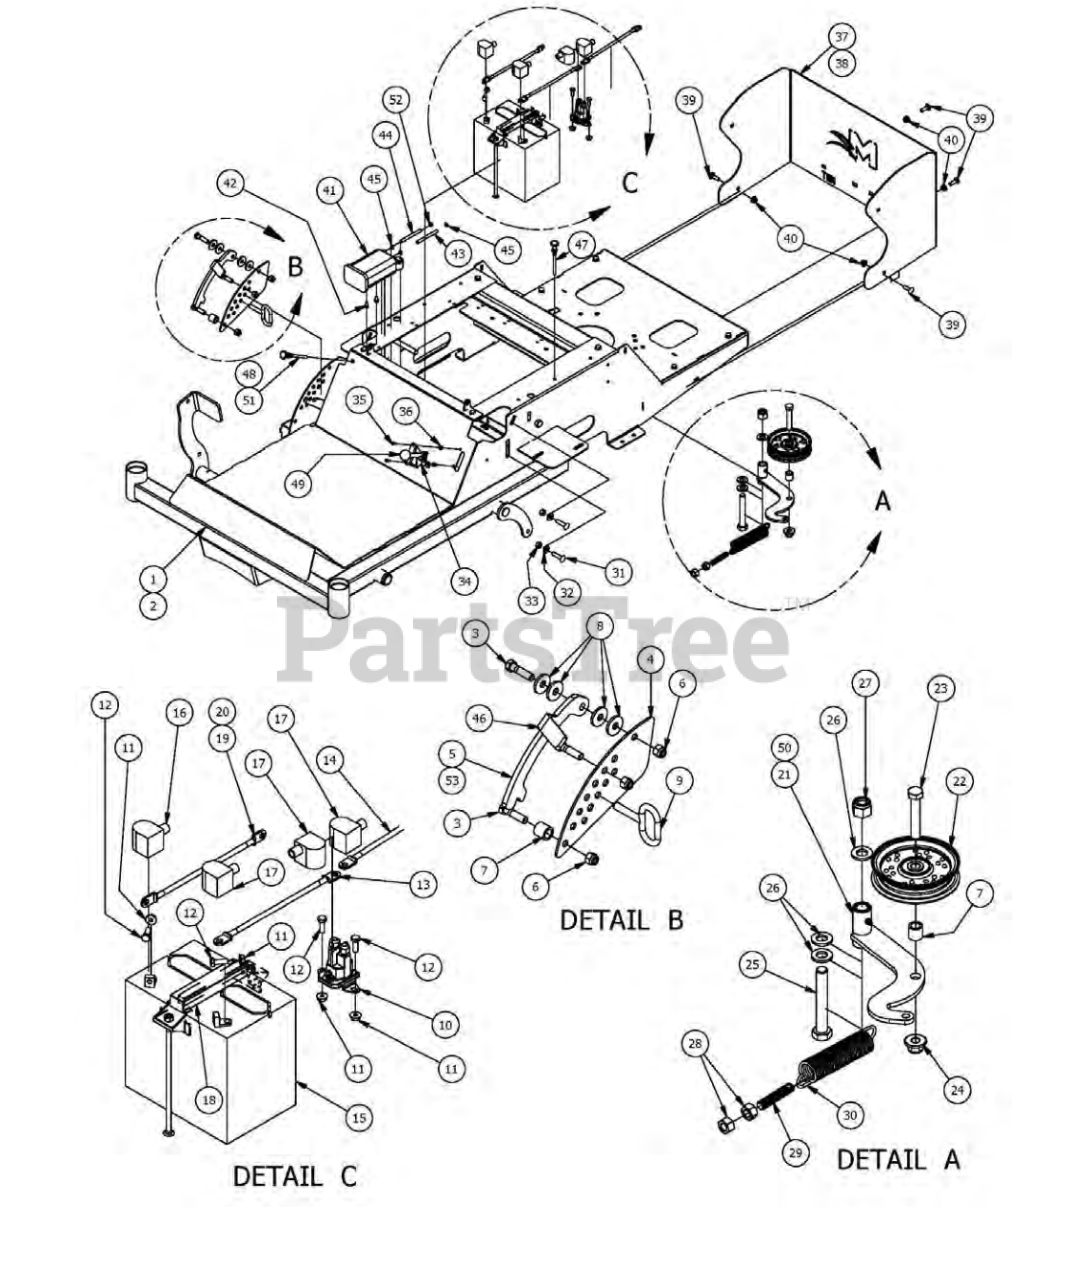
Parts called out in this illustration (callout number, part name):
1	48" MZ Frame
2	54" MZ Frame
3	3/8" x 1 1/2" Hex Bolt
4	MZ Height Indicator Plate
5	MZ Magnum Deck Level Lock Lever
6	3/8 Nylock Nut
7	Spacer 3/4 OD x 1/2 ID x 314 Length
8	390 ID Plastic Washer
9	Deck height lever pin
11	1/4-20 Hex Flange Nuts Zinc w/Serrations
12	1/4-20 x 3/4 GR 5 Hex Bolts Zinc
13	10" red battery cable
14	62" red cable
16	Black Boot For Ground Cable
18	Battery Hold Down
19	24" Ground Cable (21HP Briggs Only)
20	Ground cable
21	MZ Idler arm Bracket
22	43/4 Idler Pulley - ABFI-76
23	1/2" x 2 3/4" Hex Bolt
24	1/2-13 Nylon Flange Nut
25	5/8" x 4" Hex Bolt
26	.630 ID Plastic Washer
27	5/8 Std NC Nylock Nut
28	1/2" Hex Nut
29	All Thread-Pump Idler Tensioner
30	Deck spring big diameter
31	3/8-16 x 1-1/2 short neck bolt
32	3/8" Flat Washer
33	3/8" Hex Nut
34	Brake cable for MZ
35	10-24 X 5/8 BS Button Head Bolt
36	10-24 Nylon Insert Locknut
37	MZ Back Plate
38	Mz Back Plate (21HP Briggs)
39	5/16" x 1" Camage Bolt
40	5/16" Nylock Flange Nut Zinc
41	Carbon Canister for Magnum/MZ
42	M6-1.0 X 12MM Bolt 8.8.
43	3/16" black vinyl tubing
44	3/16" Clear Vinyl Tubing
45	3/16" Vinyl Hose Clamp
46	Deck Height Handle Grip MZ
47	Choke 42 Mz
48	Choke Kohler Magnum
49	Universal Throttle Head
50	Pump Idler Assembly (Parts 7,21,22,23,24)
51	Choke Kawasaki Magnum
52	1/4" Hose Clamp
53	MZ Deck Level Lock Lever
